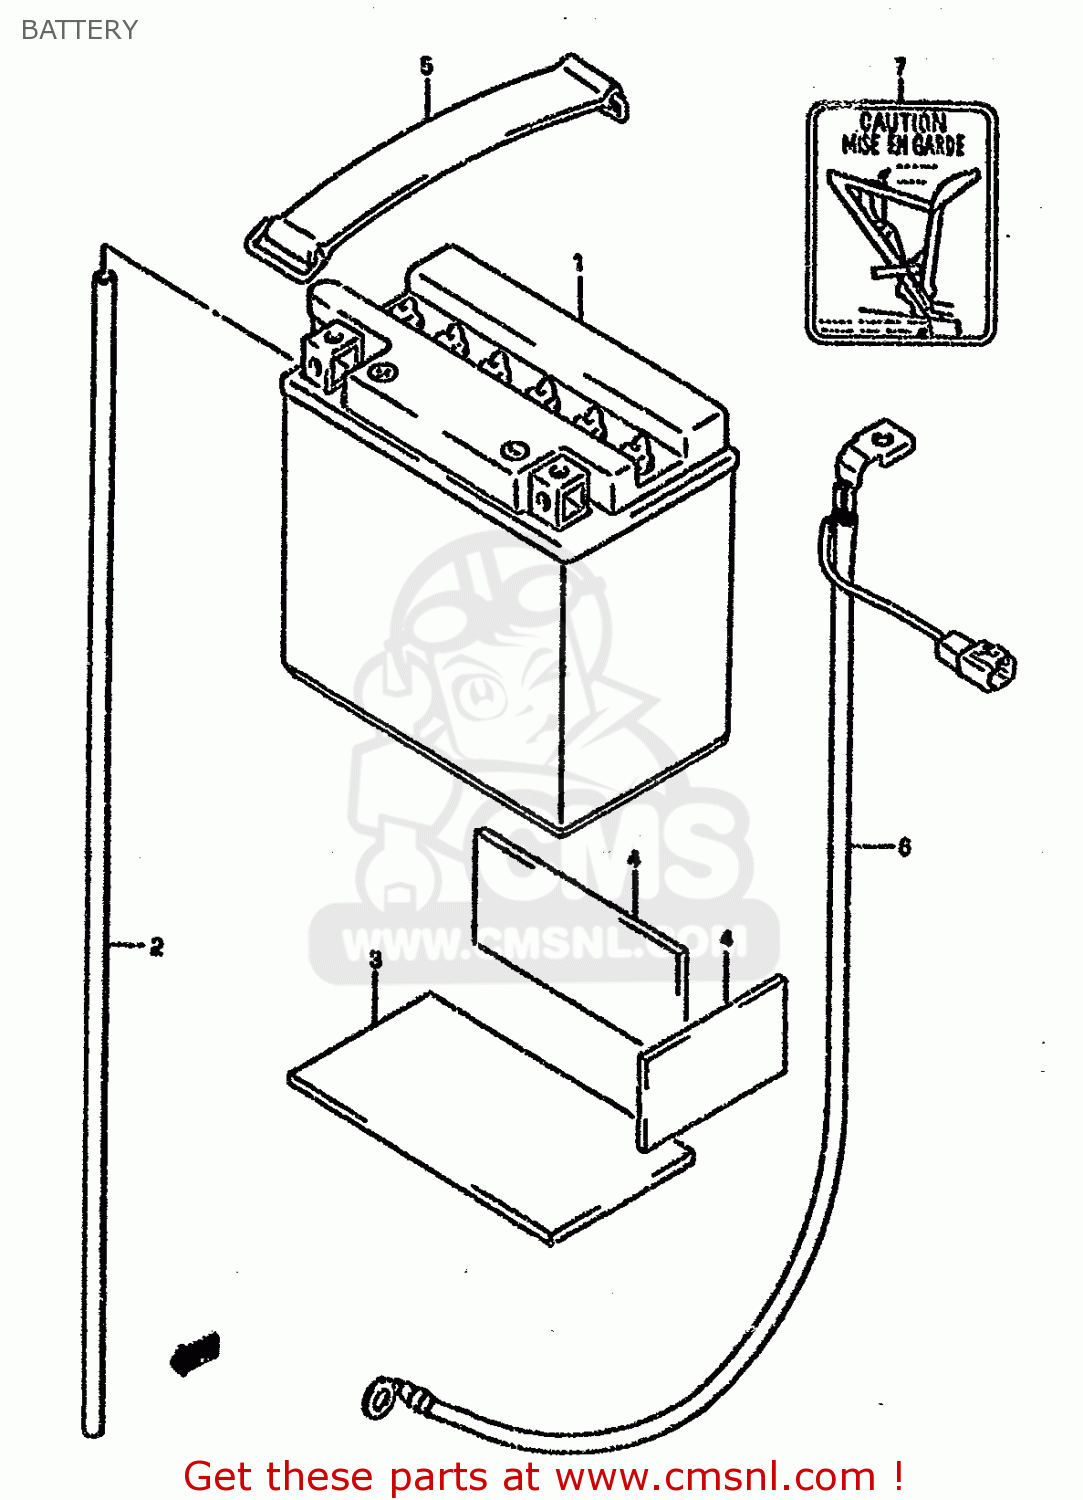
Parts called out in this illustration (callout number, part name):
1	BATTERY ASSEMBLY (12V)
2	HOSE,BATTERY EXHAUST(L:780)
3	PROTECTOR(170X95X3.0)
4	PROTECTOR(170X95X3.0)
5	BAND
6	WIRE,BATTERY MINUS LEAD
7	PLATE,BATTERY CAUTION
